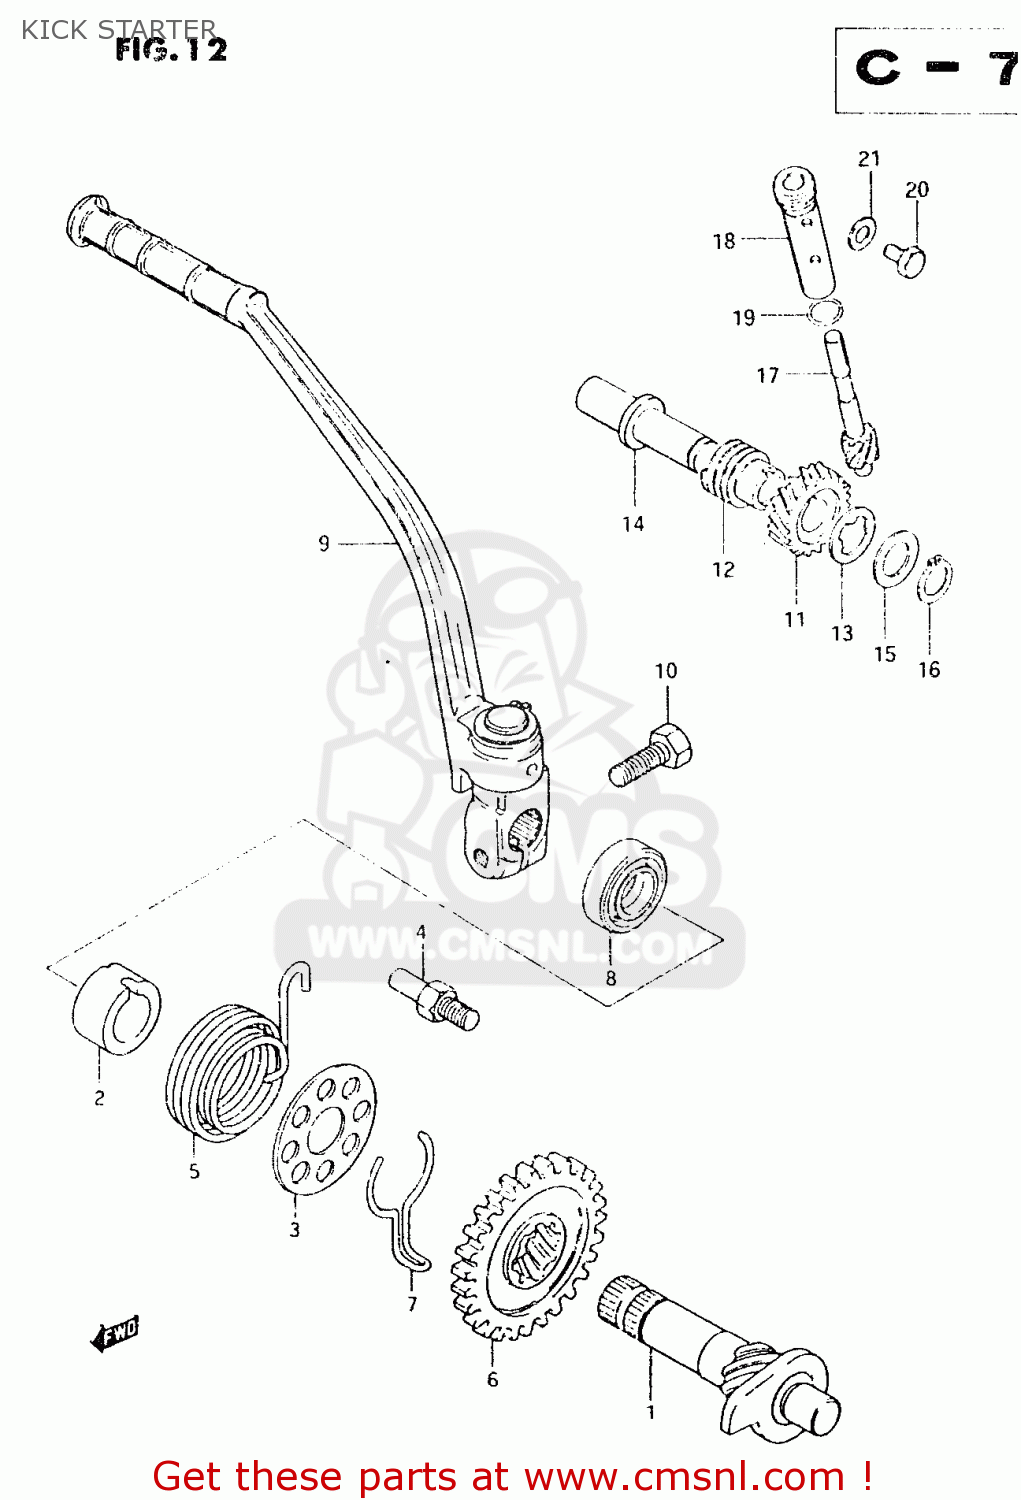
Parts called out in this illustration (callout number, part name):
1	SHAFT,KICK STARTER
2	GUIDE,KICK STARTER SFT SPRING
3	HOLDER,KICK STARTER SHAFT SPR
4	BOLT,KICK START SHAFT SPR HOOK
5	SPRING
6	GEAR, KICK STARTER DRV.
7	SPRING,KICK STARTER RETAINER
8	SEAL,OIL(14X24X6)
9	LEVER ASSY,KICK STARTER
10	BOLT
11	GEAR,TACHOMETER DRIVE(NT:19)
12	GEAR,TACH DRIVE NO.2(NT:3)
13	RETAINER,TACH DR GEAR NO.1
14	SHAFT,TACHOMETER DRIVEN GEAR
15	WASHER,THRUST
16	CIRCLIP,10MM
17	GEAR,TACHOMETER DRIVEN(NT:12)
18	SLEEVE
19	O RING(D:1.3,ID:9.6)
20	BOLT
21	GASKET(6.2X11X1).2 (NAS)
